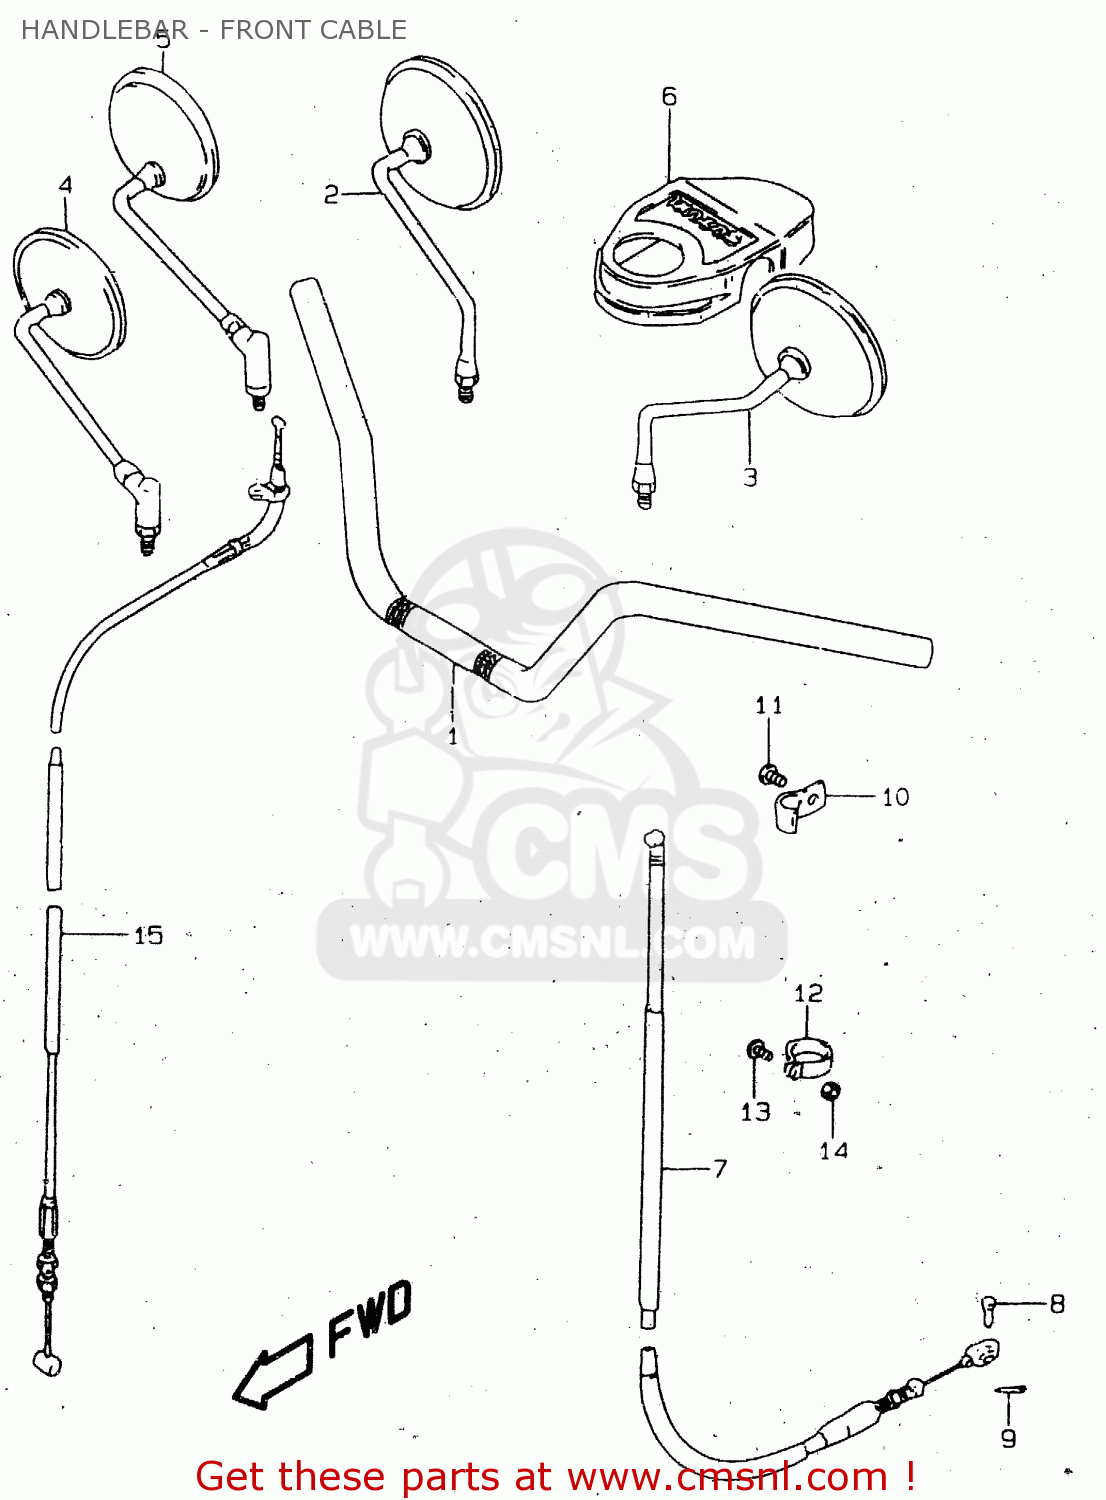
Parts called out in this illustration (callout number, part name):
1	HANDLEBAR
2	MIRROR ASSEMBLY,RIGHT
3	MIRROR ASSEMBLY,LEFT
4	MIRROR ASSY,RH
5	MIRROR ASSY,RH
6	COVER,STEERING HEAD
7	CABLE ASSEMBLY,CLUTCH
8	PIN(L:13)
9	PIN
10	CLAMP,CLUTCH CABLE NO.1
11	SCREW
12	CLAMP,CLUTCH CABLE
13	SCREW
14	NUT
15	CABLE ASSY,THROTTLE
